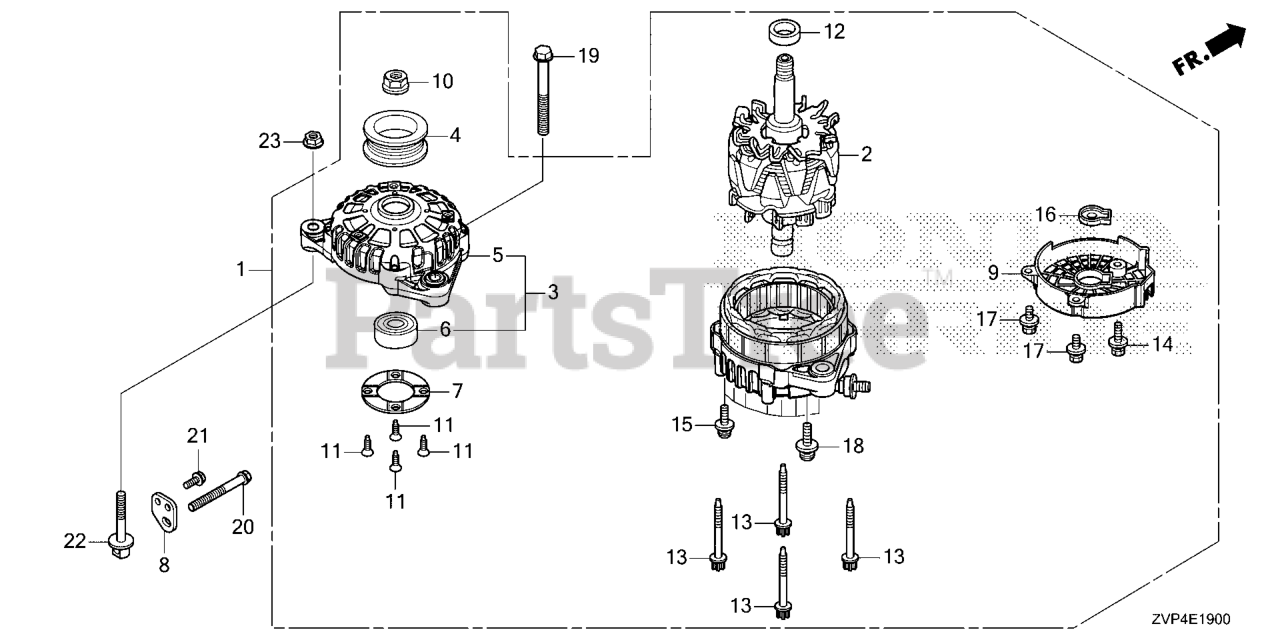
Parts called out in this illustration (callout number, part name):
1	ALTERNATOR ASSY.
2	ROTOR ASSY.
3	FRAME UNIT
5	FRAME, DRIVE END
6	BEARING, FR.
7	PLATE, RETAINER
8	STAY, ALTERNATOR
9	END COVER, RR.
10	NUT, PULLEY LOCK
11	SCREW (5X13.6)
13	THROUGH BOLT
14	BOLT-WASHER (4X17.6)
15	BOLT-WASHER (4X17.6)
16	SEAL, SLIP RING
17	BOLT-WASHER (4X12)
18	SCREW-WASH (5X6)
19	BOLT, FLANGE (10X90)
20	BOLT, SPL ADJ
21	BOLT, FLANGE (6X16)
22	BOLT, TENSIONER
23	NUT, FLANGE (8MM)
